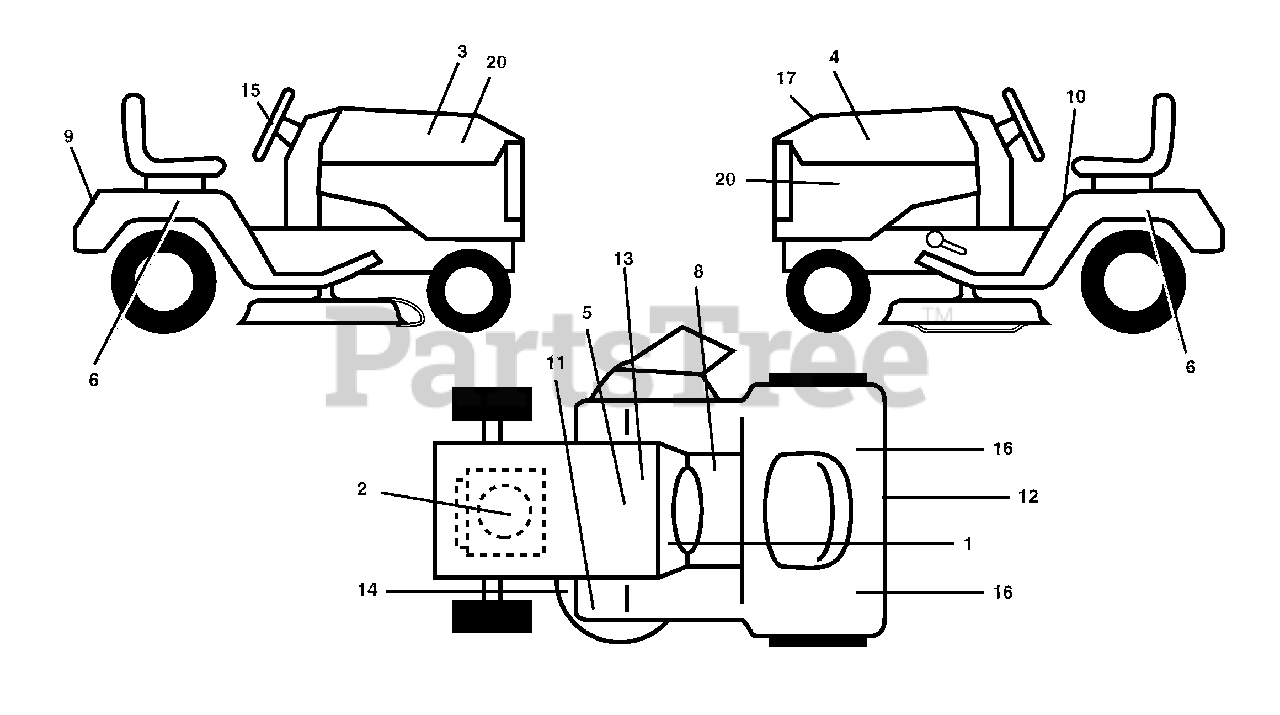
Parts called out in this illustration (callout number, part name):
1	Decal, Operating Instruction
2	Decal, Engine
3	Decal, Hood, RH
4	Decal, Hood, LH
5	Decal, Battery
6	Decal, Fender Auto
7	Decal,Warning Multi-Language
8	Decal, Brake Parking Saddle
9	Decal, Fender
10	Decal,Danger
11	Decal, Clutch/Brake
12	Decal, D-Bar Ctrl. Mvt Hyd YT/GT
13	Decal, Bat. DAN/POI P/L Symbols
14	Decal, V-Belt Schematic
15	Decal, Ins. Strg Whl
16	Reflector Tail Light
17	Decal, RPLT
20	Decal, Side Pnl
